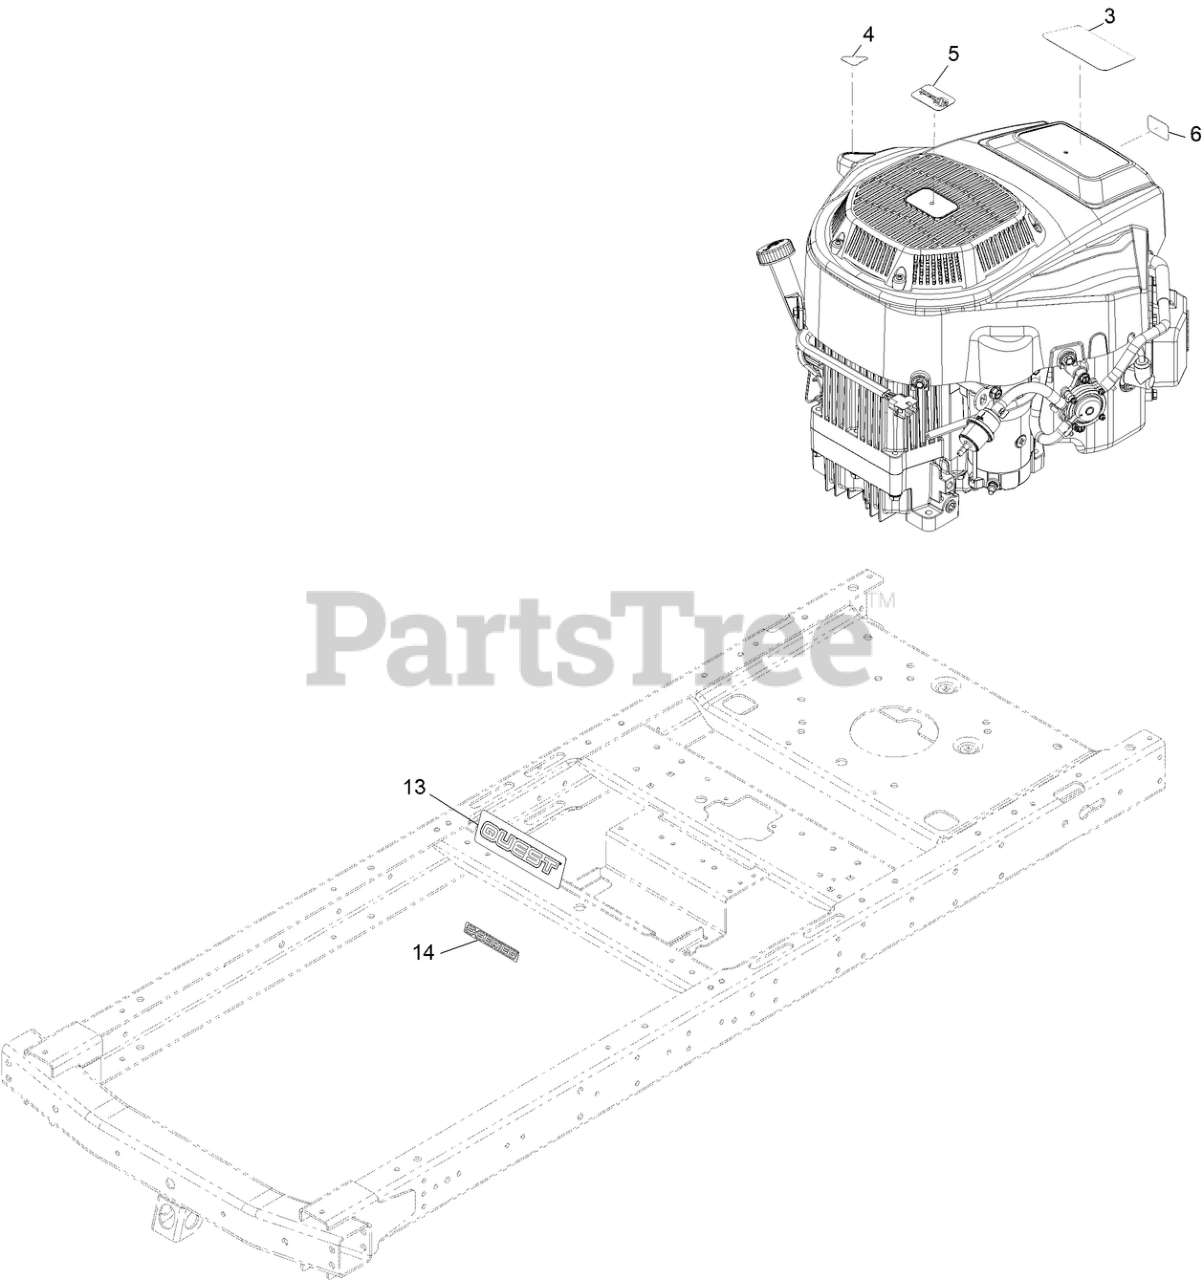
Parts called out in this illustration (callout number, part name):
3	DECAL-ENGINE 708 V-TWIN EXMARK
4	DECAL-DRAIN, OIL
6	PLACARD-INTAKE, EXMARK
13	DECAL-QUEST LOGO
14	DECAL-S-SERIES
